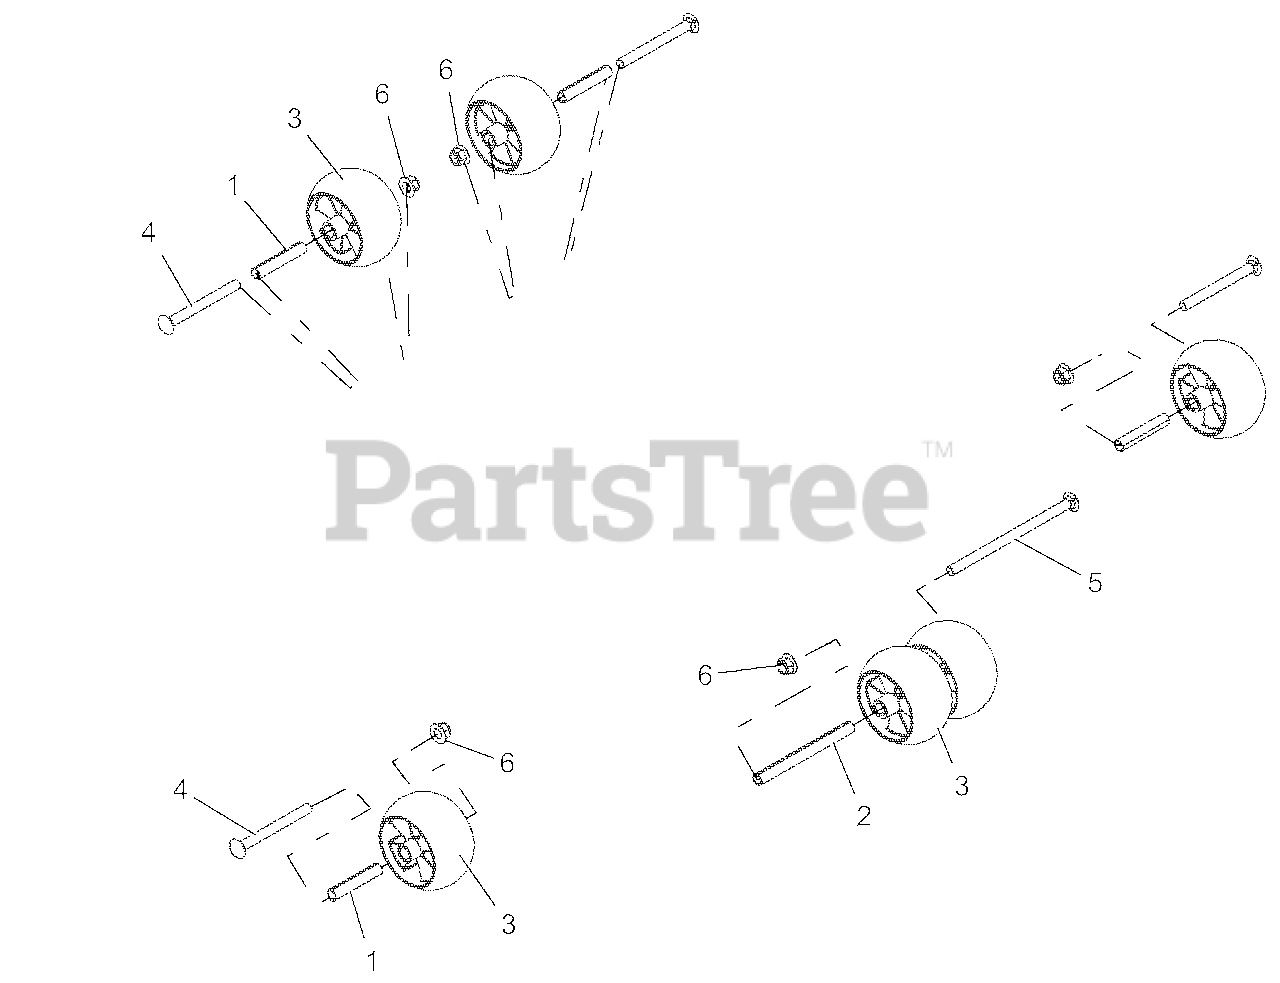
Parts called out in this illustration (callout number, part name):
1	SPACER, .510 x .625 x 3.35
2	SPACER, .510 x .625 x 6.70
3	ANTI-SCALP WHEEL - 5 x 3 CTR
4	BLT-RDHDSQNK .50-13 x 5.00 G5 YWZC
5	BLT-RDHDSQNK .50-13 x 8.50 Y
6	NUT-LK-NYL-FLG .50-13 YWZC
